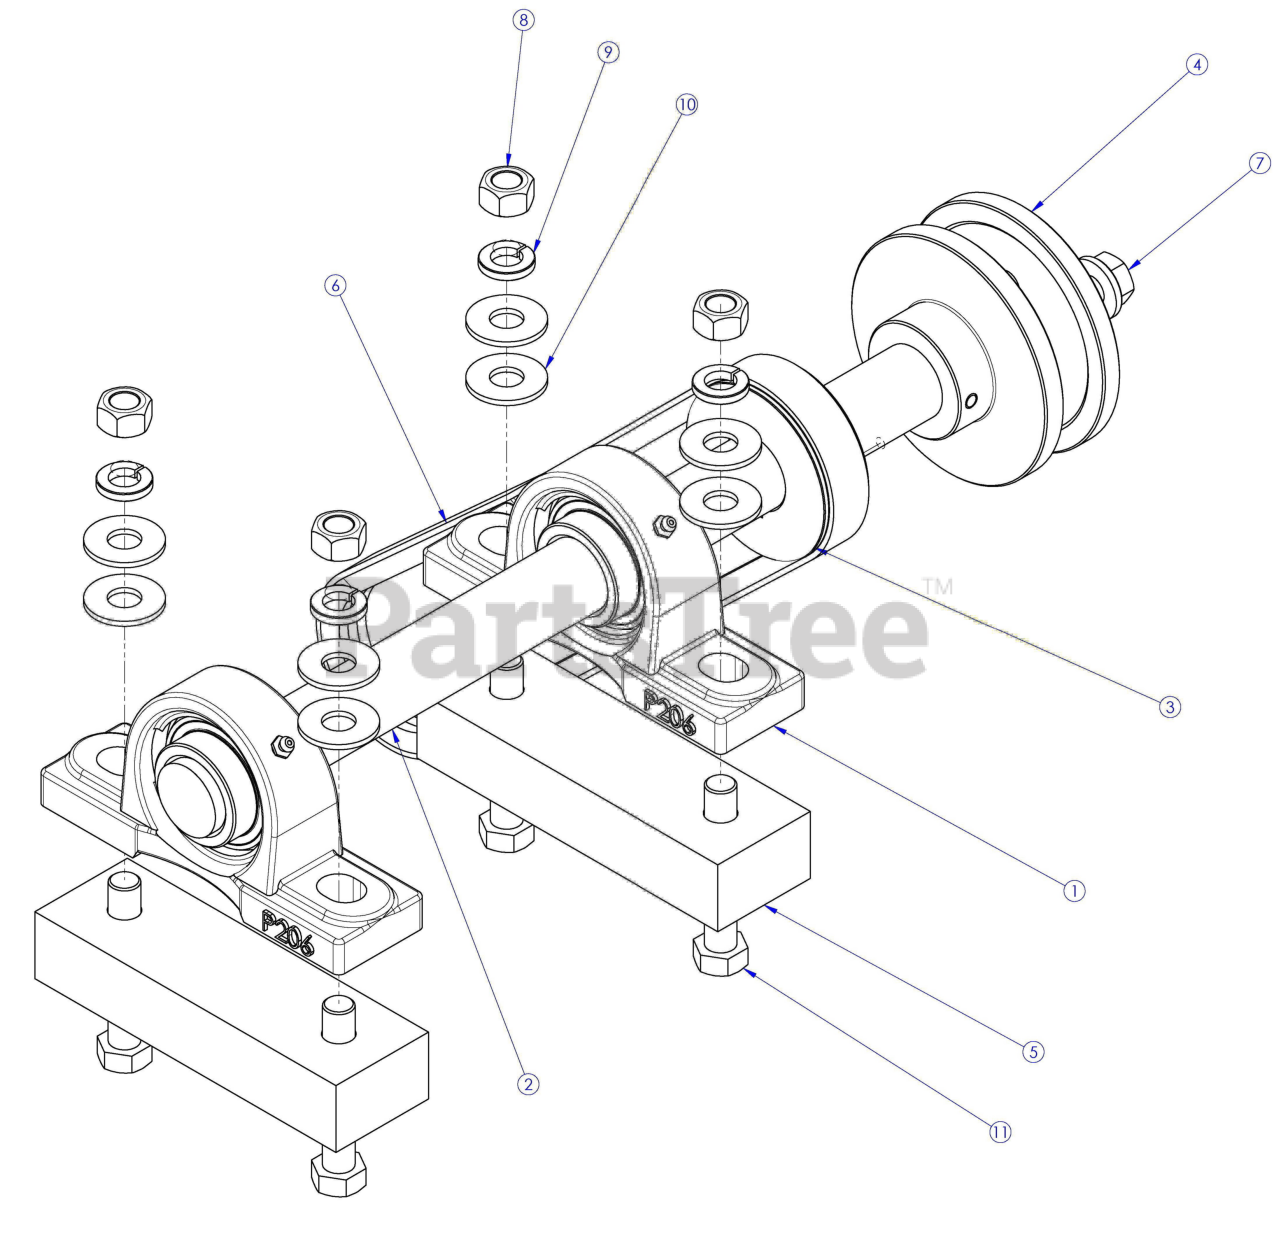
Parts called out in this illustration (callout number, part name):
1	Bearing, Pillow Block, 1.25"Id
2	Blade Shaft
3	Sheave, 2/3V 3.00 Od X 1.25 Id
4	Arbor Washer Outer G20 New Style
5	Spacer, Bearing
6	Belt, 3Vx315
7	Flange Hex Bolt 1/2-13 X 1
8	Nut, 1/2-20 Hex, Gr5 Zinc
9	Washer, Split 1/2" S.S.
10	Washer, 1/2" Flat S.S.
11	HHB 1/2-20 X 3 Gr8
